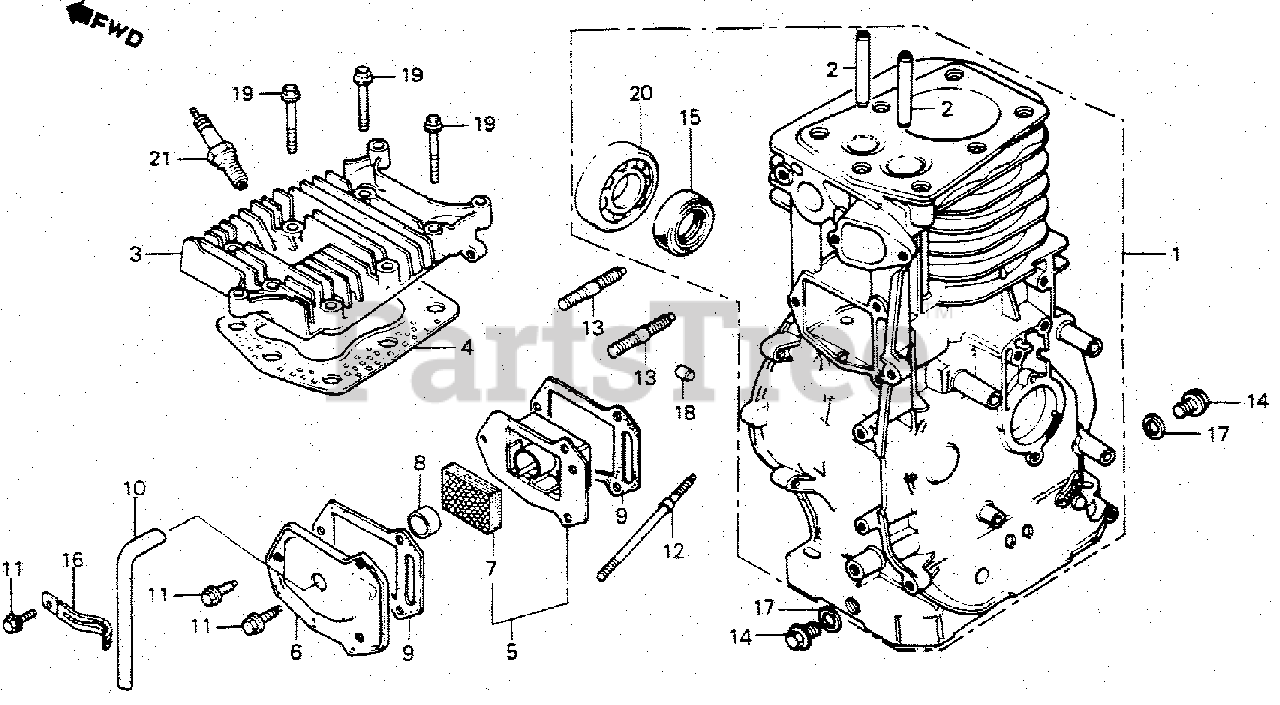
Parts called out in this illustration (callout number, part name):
1	CYLINDER ASSY.
2	GUIDE, VALVE (OS)
3	CYLINDER HEAD
4	GASKET, CYLINDER HEAD
5	CASE, BREATHER
6	COVER, TAPPET ROOM
7	FILTER, BREATHER
8	SEAL, BREATHER
9	GASKET, TAPPET COVER
10	TUBE, BREATHER
11	BOLT, FLANGE (6X12) (CT200)
12	BOLT, STUD (6X89)
13	BOLT, STUD (8X35)
14	BOLT, DRAIN PLUG
15	OIL SEAL (25X41X6)
16	CLIP, CABLE
17	WASHER, DRAIN PLUG (12MM)
18	PIN A, DOWEL (8X14)
19	BOLT, FLANGE (8X45)
20	BEARING, RADIAL BALL (6205)
21	SPARK PLUG (W14F-U) (DENSO)
21	SPARK PLUG (W14FR-U) (DENSO)
21	SPARK PLUG (BP-4HS-10) (NGK)
21	SPARK PLUG (BP4HS-10) (NGK)
21	SPARK PLUG (W14FP-UL10)
21	SPARK PLUG (W14FPR-UL10)
21	SPARK PLUG (W20FS-U) (DENSO)
21	SPARK PLUG (W20FSR-U) (DENSO)
21	SPARK PLUG (W20FP-U10) (DENSO)
